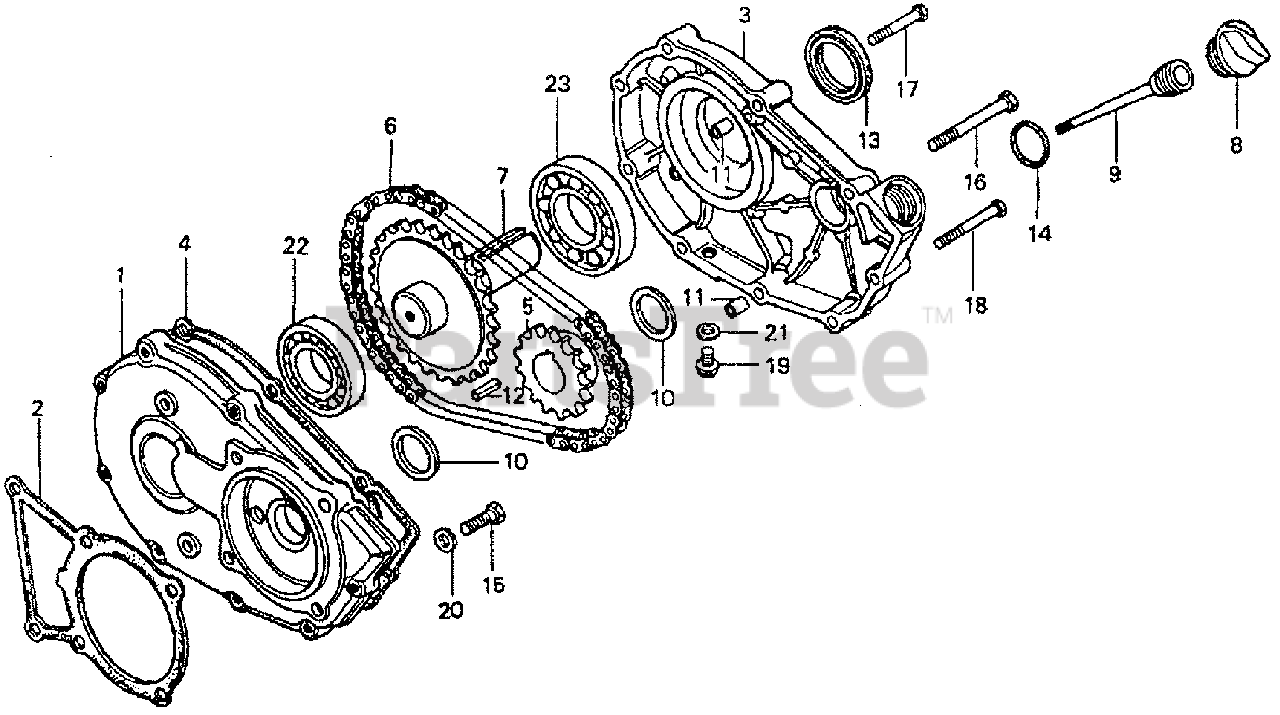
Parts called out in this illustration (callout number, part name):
1	CASE, REDUCTION
2	GASKET, REDUCTION CASE (NOT AVAILABLE)
3	COVER, REDUCTION
4	GASKET, REDUCTION COVER
5	SPROCKET, DRIVE
6	CHAIN, DRIVE (RK428FX38LE)
7	SHAFT, P.T.O.
8	CAP, REDUCTION OIL (GRAY)
8	CAP, REDUCTION OIL
9	DIPSTICK, OIL
10	WASHER C, THRUST (25MM)
11	PIN, DOWEL (8X10)
12	KEY, DRIVE SPROCKET
13	OIL SEAL (35X50X8)
14	O-RING (26X2.7)
15	BOLT, HEX. (8X25)
16	BOLT, HEX. (8X65)
17	BOLT, HEX. (6X40)
18	BOLT, HEX. (6X45)
19	BOLT, DRAIN PLUG (12MM)
20	WASHER, PLAIN (8MM)
21	WASHER, DRAIN PLUG (12MM)
22	BEARING, RADIAL BALL (6206)
23	BEARING, RADIAL BALL (6207)
